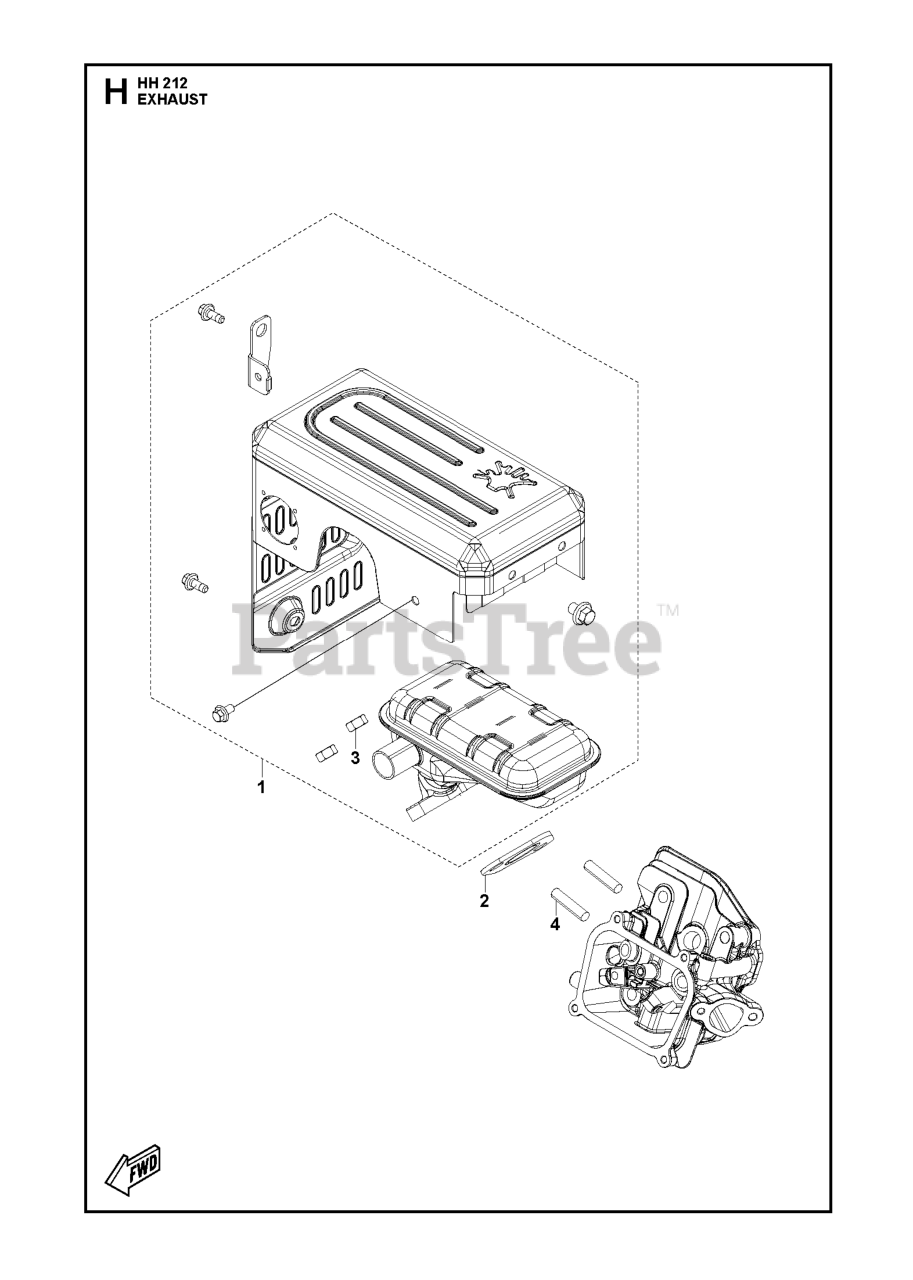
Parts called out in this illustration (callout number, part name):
1	MUFFLER ASSY
2	GASKET MUFFLER GASKET
3	NUT
